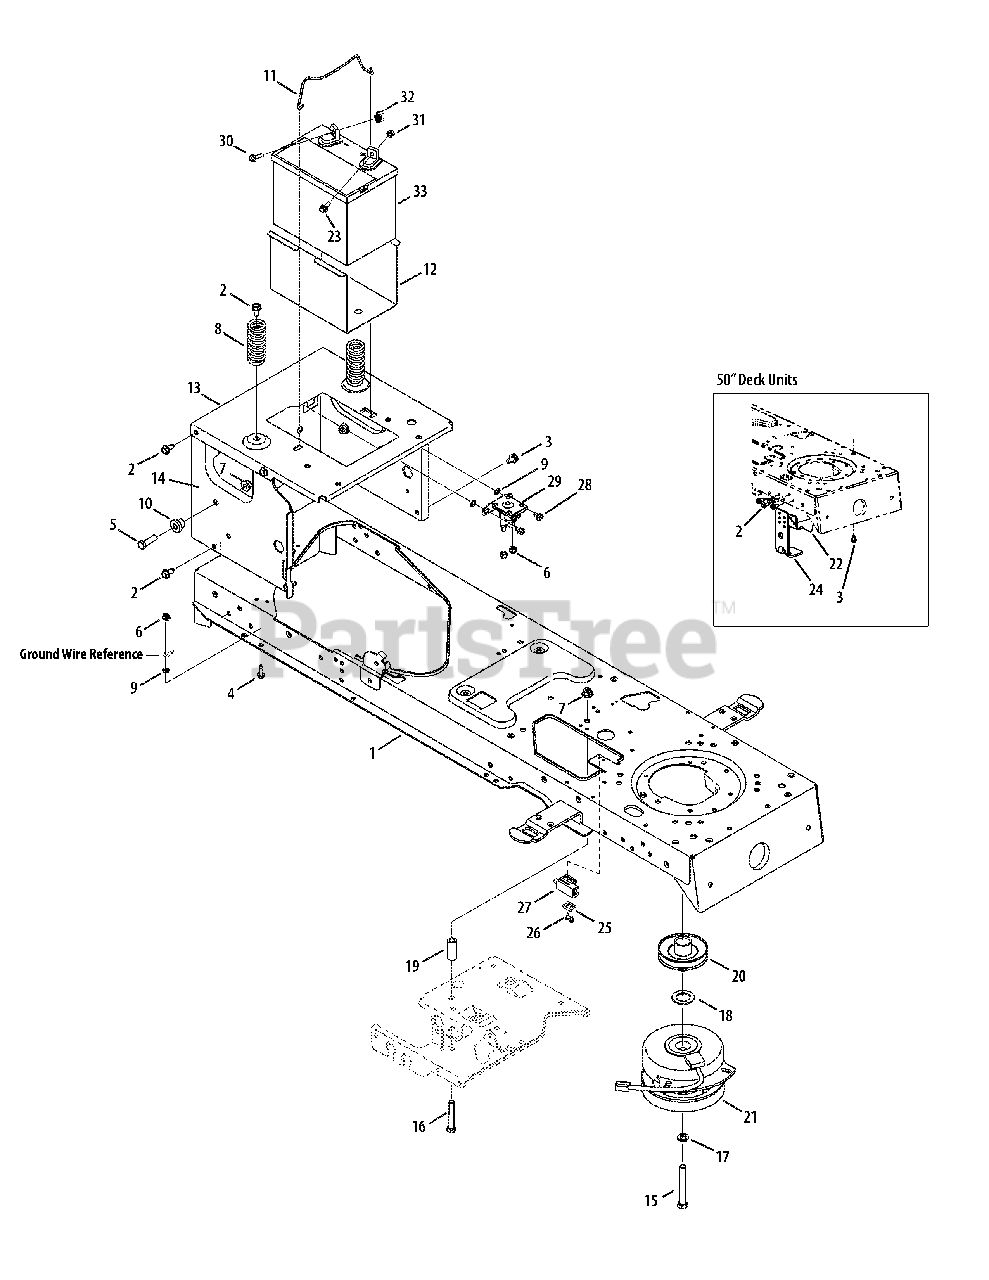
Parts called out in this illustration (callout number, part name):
1	Frame Assembly, Lower
2	Screw, 5/16-18 x 0.75
3	Screw, 5/16-18, 0.500
4	Screw, 1/4-20, 0.750
5	Screw, 3/8-16, 1.25, Gr5
6	Nut, Flange Lock, 1/4-20
7	Nut, Flange Lock, 3/8-16
8	Spring, Compress., 1.28 x 3.125
9	Washer, Lock, 1/4, External
10	Spacer, Shoulder,.38 x 1.0 x.70
11	Hold Rod, Battery
13	Seat Bracket, Frame
15	Screw, 7/16-20, 3.50, Gr5, Lock
16	Screw, 3/8-16, 2.25, Gr5
17	Lock Washer, 7/16
18	Washer, Flat, 1.031 x 1.620 x.095
19	Spacer,.385 ID x.635 OD x 1.54
20	Pulley, Engine, 3.56 Diameter
21	PTO Clutch, Electric (50" Deck Units)
22	Clutch Bracket
23	Screw, Shoulder,.250 x.15, 1/4-20
24	Deck Bracket, Up-Stop (50" Deck)
25	Switch Plate
26	AB Screw, #10-16 x.500
28	Screw, 1/4-20, 0.50
29	Solenoid, 12V, 100 Amp
30	Hex Flange Bolt, 1/4-20,.75
31	Nut, Sems, 1/4-20
32	Nut, Wing, 1/4-20
33	Battery, 245 CCA
